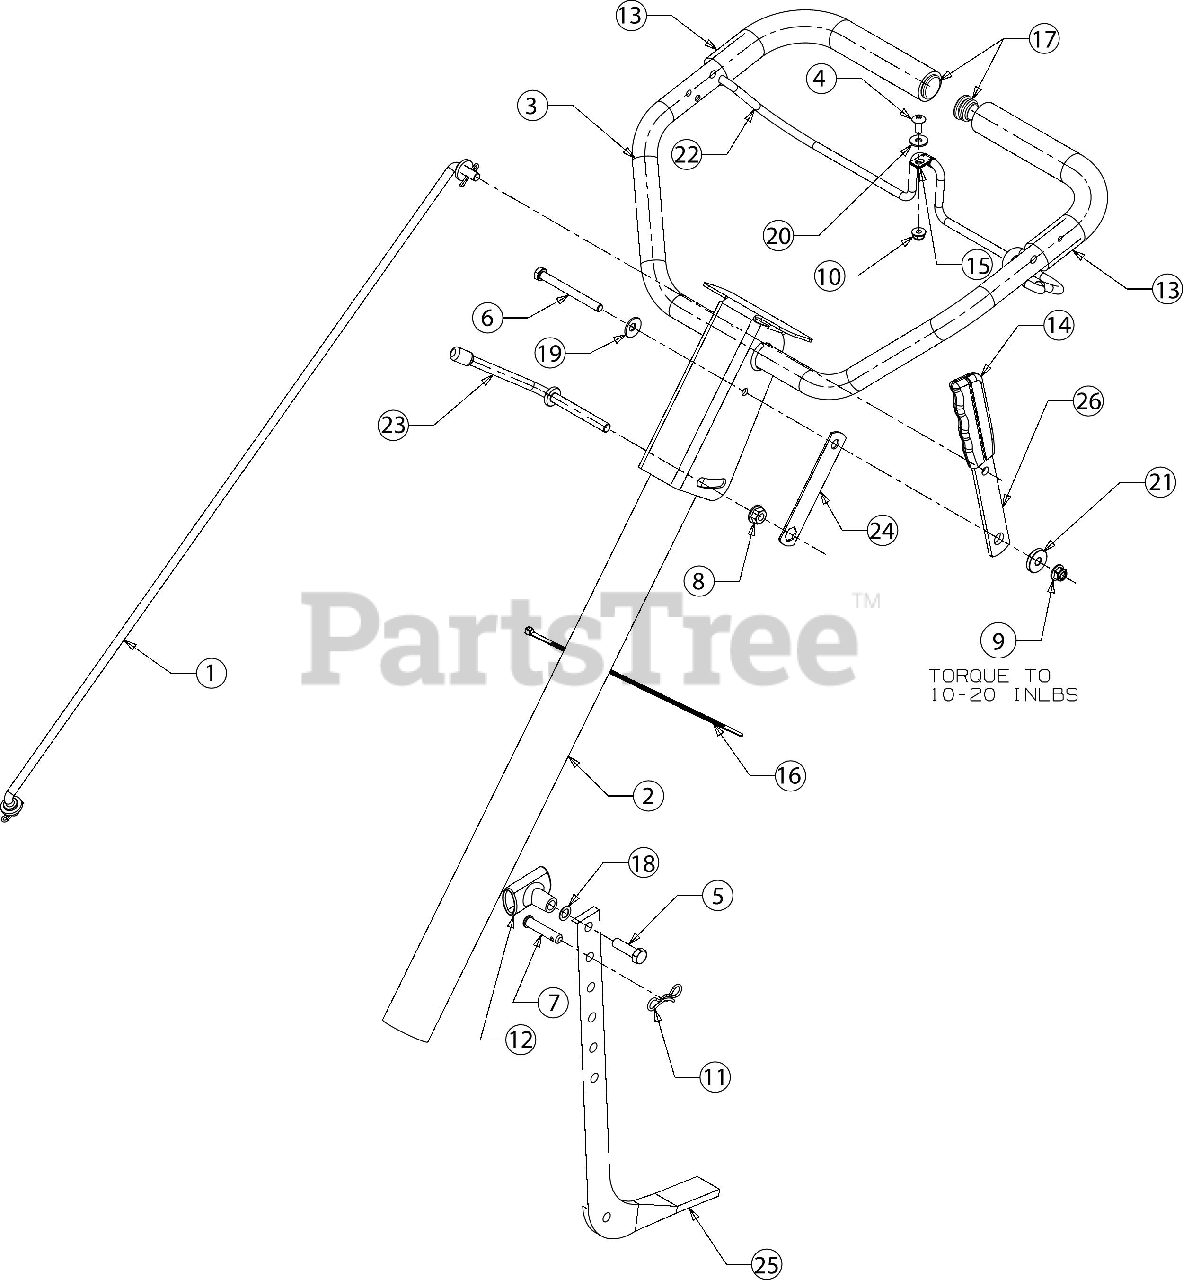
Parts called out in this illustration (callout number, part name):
1	SHIFT ROD
1	RUBBER WASHER
1	COTTER PIN .072 DIA
2	LOWER HANDLE ASSEMBLY
3	HANDLE ASSEMBLY-UPPER
4	SCREW 1/4-20 X .625
5	SCREW 3/8-16 X 1.25 GR5
6	SCREW 5/16-18 X 3.25 GR5
7	CLEVIS PIN .375 X .1.75
8	FLANGE HEX NUT
9	FLANGE LOCK NUT 5/16-18
10	FLANGE LOCK NUT
11	PIN:COTTER
12	THROTTLE KNOB
13	FOAM GRIP .970 X 11.0
15	MOUNTING CLAMP
18	FLAT WASHER
19	BELL WASHER .337 X.867 X .057
20	FLAT WASHER
21	SHOULDER SPACER
24	RETAINER BRACKET
25	DEPTH BAR ASSEMBLY
26	SHIFT ROD LEVER
